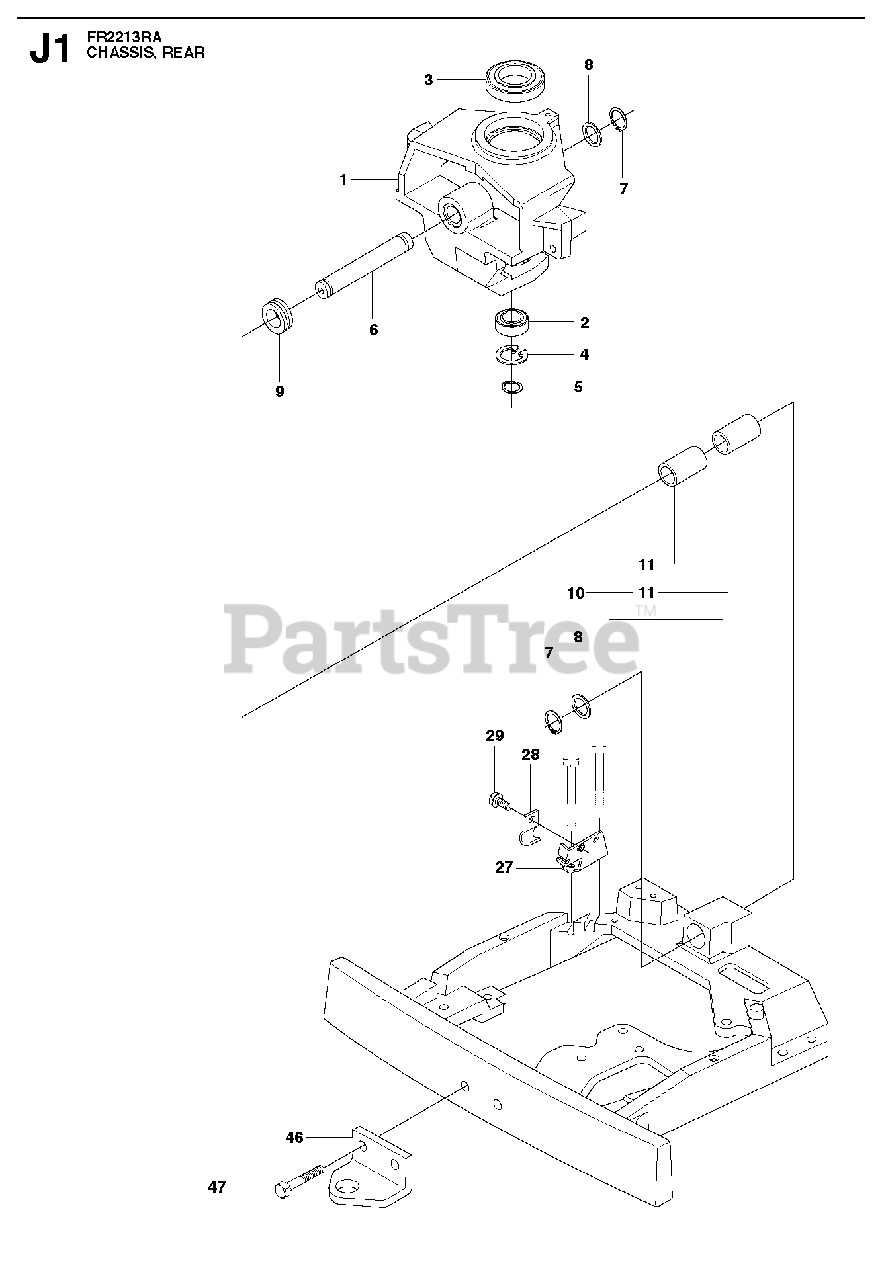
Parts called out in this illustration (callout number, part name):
2	BALL BEARING 6005-2RS
3	BALL BEARING 6010 2RS1
4	CIRCLIP SGH 47
5	RETAINING RING SGA 25
7	RETAINING RING SGA 25
11	BUSHING
46	DRAW RING
47	SCREW M10X25
